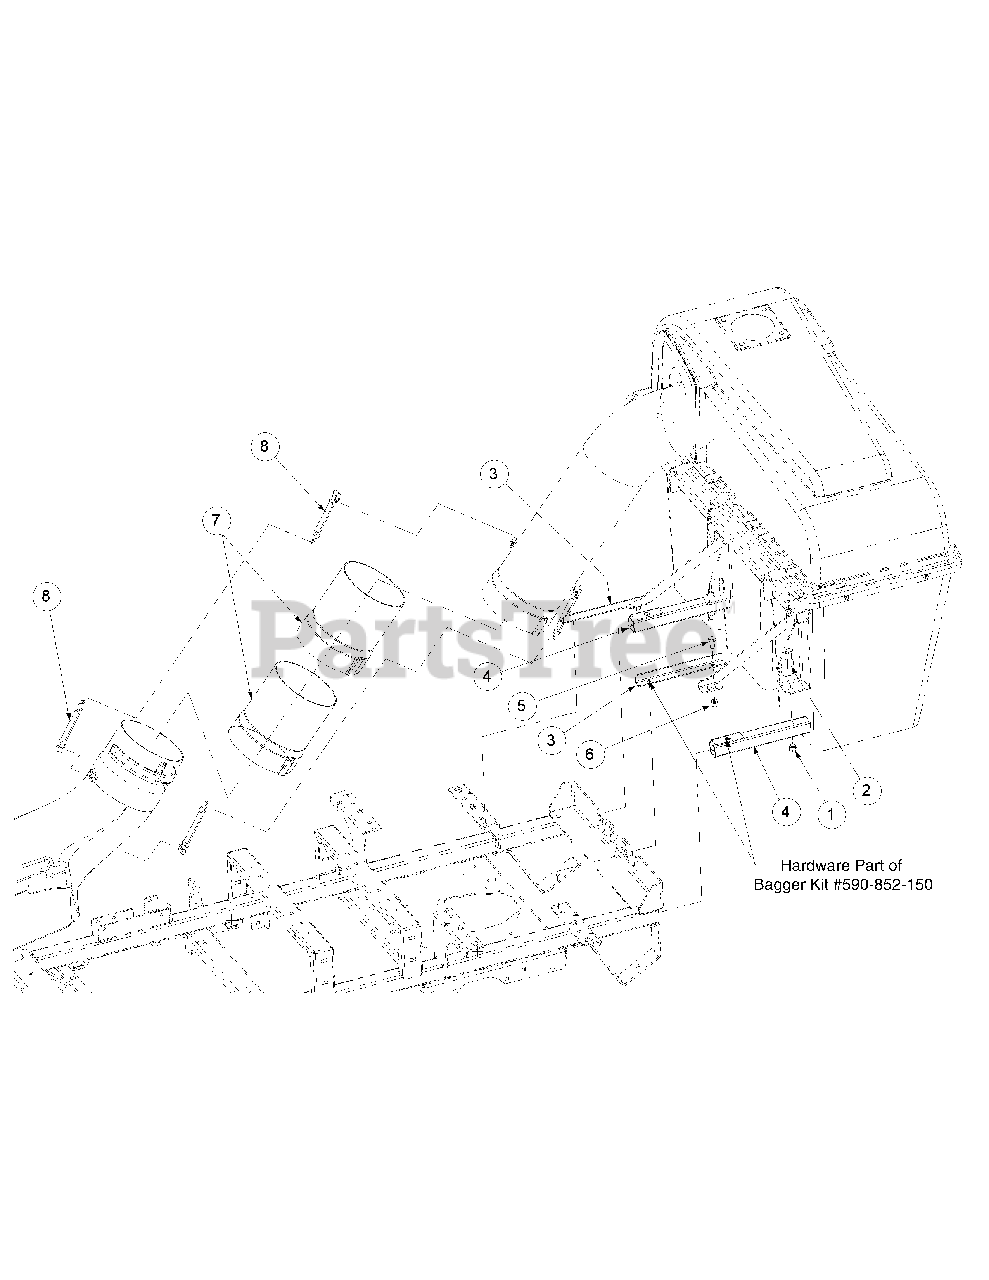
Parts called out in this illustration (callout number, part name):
1	Nut, 1/2-13
2	Hex Cap Screw, 1/2-13 x 3.00
3	Upright Extension Bracket
4	Upright Mount Extension Assembly
5	Hex Cap Screw, 1/2-13 x 1.00
6	Nut, 1/2-13, Hexlock Nylon
7	Extension Tube, 8" Dia. x 10"
8	Retainer Strap
